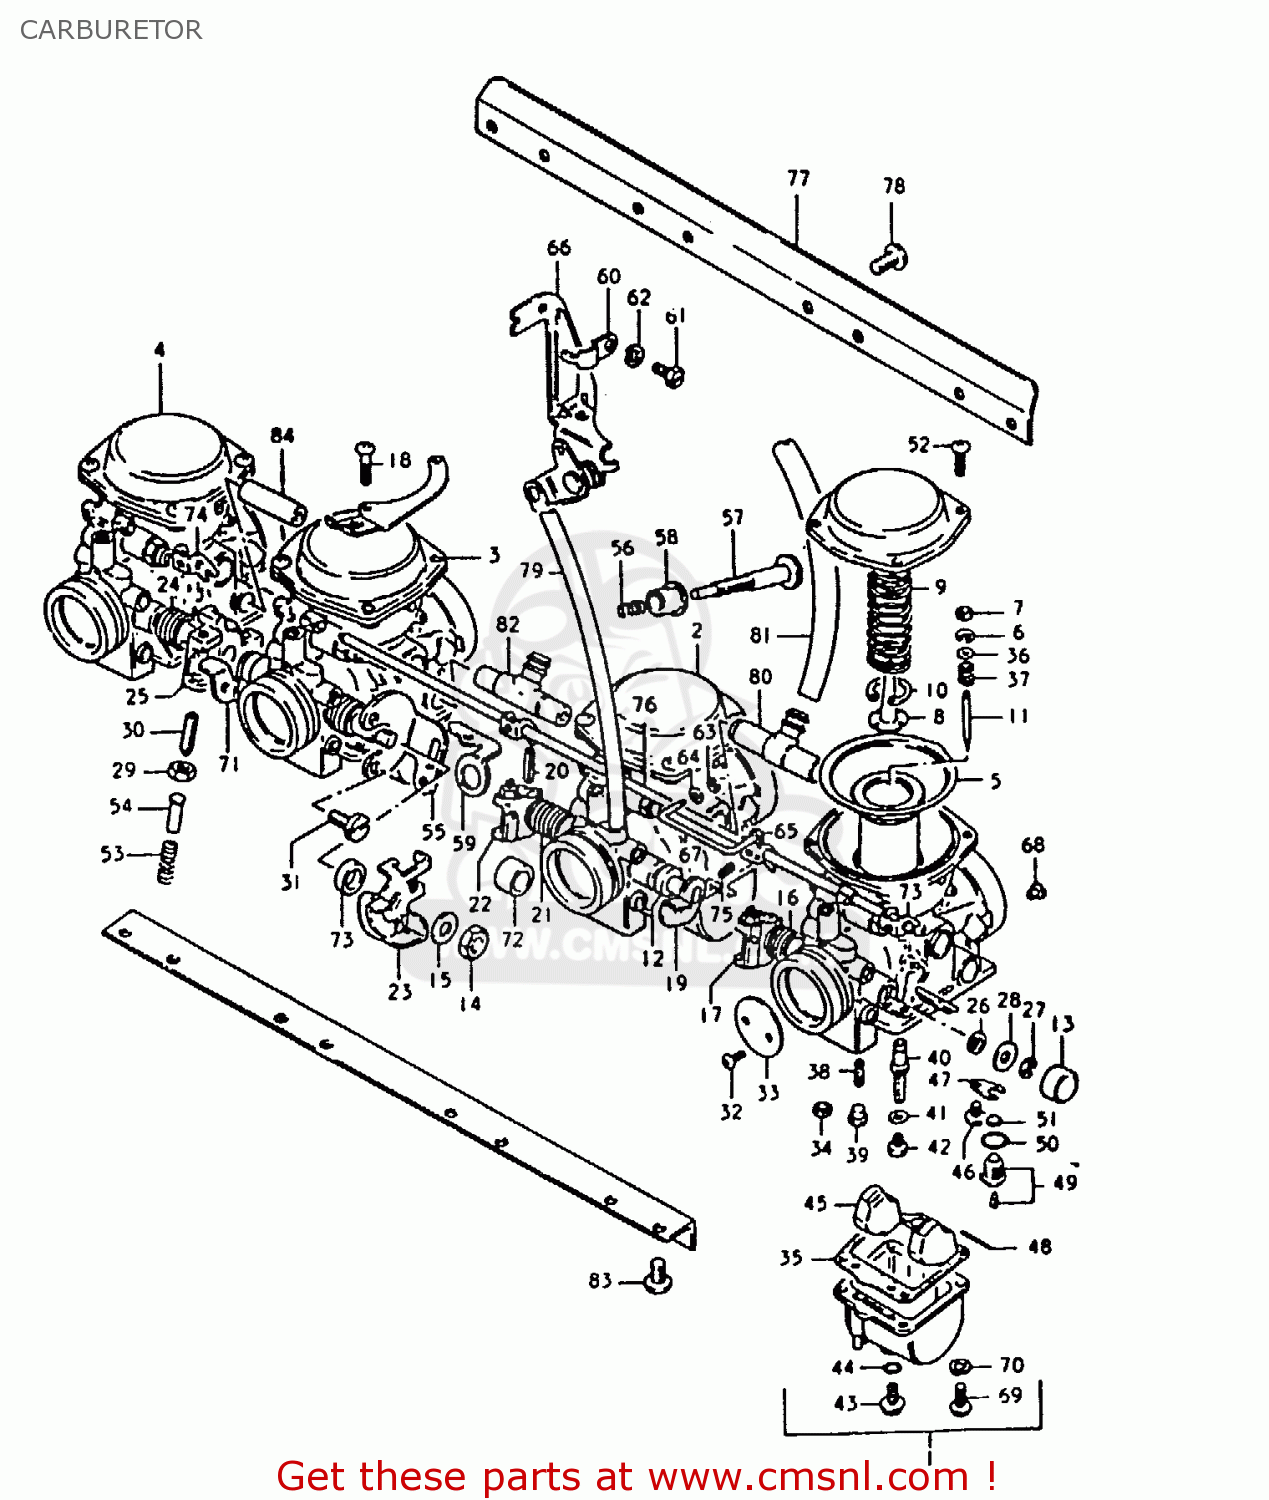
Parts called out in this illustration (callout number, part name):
1	CARBURETOR, NO.1
2	CARBURETOR, NO.2
3	CARBURETOR, NO.3
4	CARBURETOR, NO.4
5	DIAPHRAGM ASSEMBLY
6	CLIP,NEEDLE
7	RING
8	HOLDER,GUIDE
9	SPRING
10	E RING
11	NEEDLE, JET (5057-2)
12	GASKET
13	CAP
14	NUT
15	WASHER
16	SPRING,THROTTLE SHAFT
17	SHAFT,THROTTLE
18	SCREW
19	SHAFT,THROTTLE
20	PIN,THROTTLE SHAFT
21	SPRING,THROTTLE SHAFT
22	LEVER,THROTTLE SHAFT
23	LEVER ASSEMBLY,THROTTLE
24	SPRING,THROTTLE SHAFT
25	SHAFT,THROTTLE
26	SEAL
27	E RING
28	GASKET,THROTTLE SHAFT (NAS)
29	NUT
30	SCREW
31	SCREW
32	SCREW
33	VALVE,THROTTLE (BUTTERFLY)
34	GASKET (NAS)
35	GASKET,FLOAT CHAMBER (NAS)
36	WASHER
37	SPRING
38	JET
39	PLUG,NEEDLE JET
40	JET, NEEDLE (X-8)
41	WASHER,NEEDLE NOZZLE
42	JET
43	PLUG,DRAIN
44	GASKET (NAS)
45	FLOAT
46	SCREW
47	PLATE
48	PIN,FLOAT
49	VALVE ASSEMBLY,NEEDLE
50	O RING
51	FILTER
52	SCREW
53	SPRING,THROTTLE SCREW
54	PIN,THROTTLE LEVER
55	BRACKET,THROTTLE ADJUST
56	SPRING
57	SCREW
58	BUSH
59	BRACKET,THROTTLE ADJUST
60	BRACKET,STARTER
61	BOLT
62	LOCK WASHER
63	CAP,LEVER
64	SEAT,SPRING
65	LEVER ASSY
66	BRACKET
67	ROD,STARTER LEVER
68	JET,PILOT AIR(1.5)
69	SCREW
70	LOCK WASHER
71	SHAFT,THROTTLE
72	RING
73	RING
74	LEVER
75	SCREW
76	SHAFT,STARTER
77	BRACKET
78	SCREW
79	HOSE
80	NIPPLE
81	HOSE
82	NIPPLE
83	SCREW 6X12
84	NIPPLE
